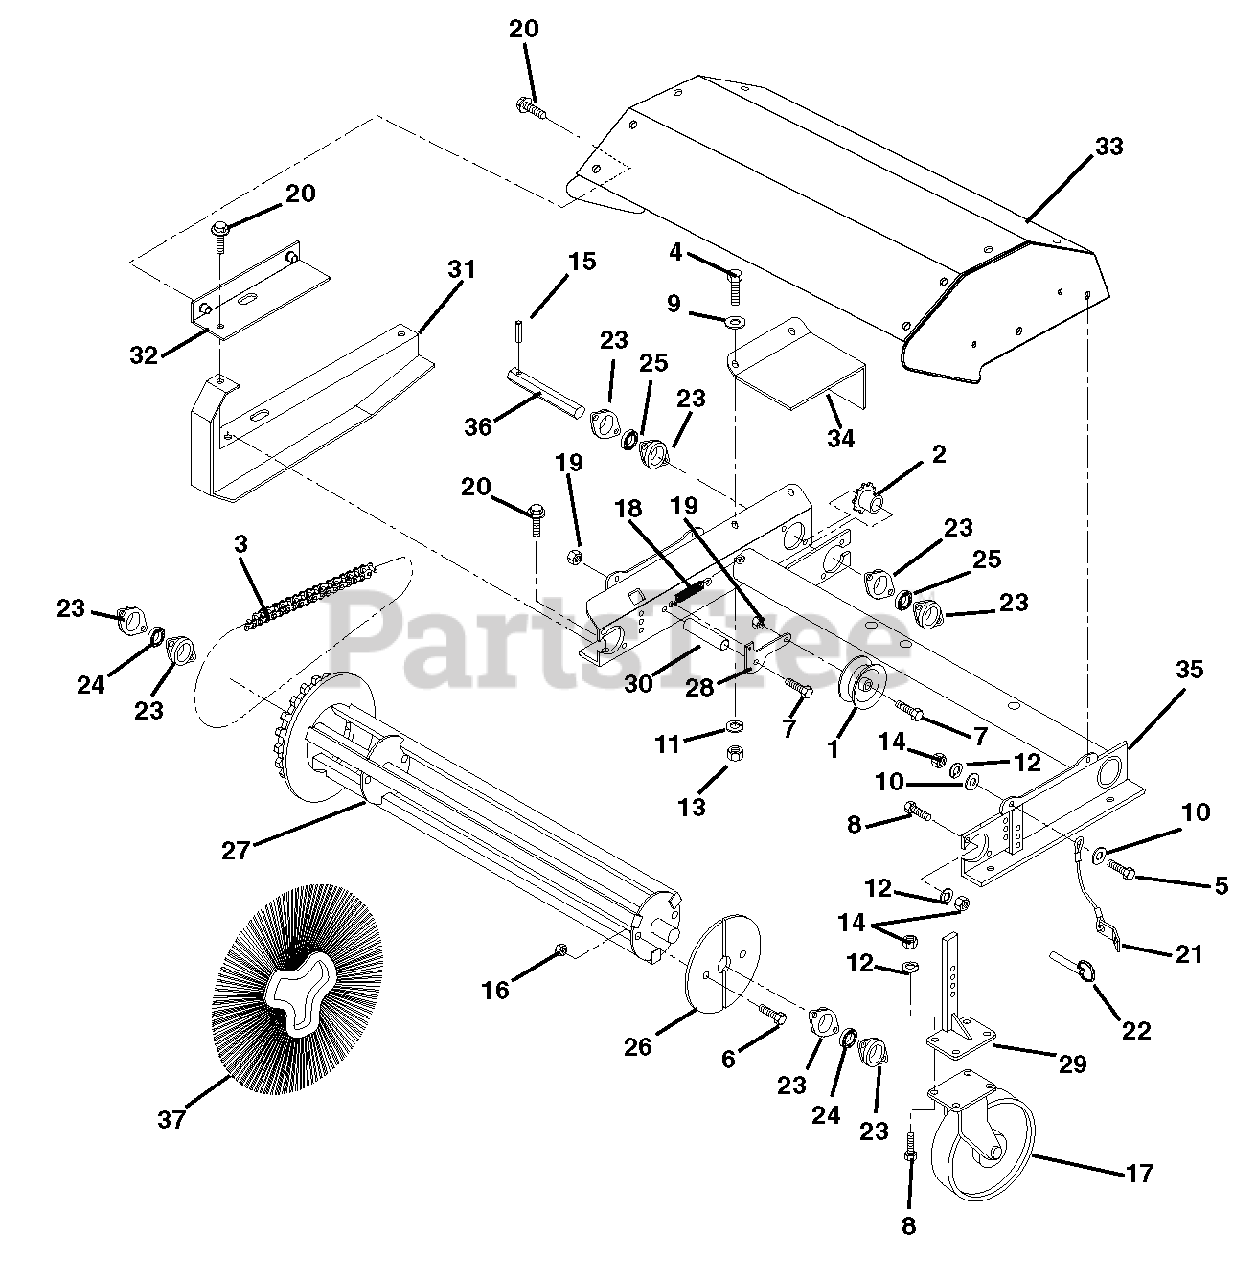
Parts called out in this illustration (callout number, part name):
1	Chain Tightener
2	Sprocket
3	Chain, Assembly #40 x 106
4	Bolt, Hex .25-20 x .75 Grade 5
5	Bolt, Hex .31-18 x 1.00 Grade 5
6	Bolt, Hex .31-18 x 2.25 Grade 5
7	Bolt, Hex .38-16 x 1.50 Grade 5
8	Bolt, Hex .31-18 x .75 Grade 5
9	Washer, Flat Steel .28 x .62 x .065
10	Washer, Flat Steel .31 x .73 x .065
11	Washer, Lock .25 x .062 Regular
12	Washer, Lock .31 x .078 Regular
13	Nut, Hex .25-20
14	Nut, Hex .31-18
15	Pin, Spring Lok .19 x 1.25
16	Nut, Lok Stamped .31-18
17	Wheel, 5 inch Diameter
18	Spring, Tension
19	Nut, Locking Center .38-16
20	Screw, Gear 10.9 M6 x 1-20
21	Lanyard Cable
22	Pin, Spring Ball .375 x 1.00
23	Flange, Spherical
24	Bearing, Spherical
25	Bearing, Ball
26	Retainer Plate
27	Weldment, Core
28	Arm, Idler
29	Weldment, Caster Leg
31	Shield, Chain
32	Shield Chain Top
33	Weldment, Faceted Hood
34	Shield, Input
35	Weldment, Broom Frame
36	Shaft, Hex 20.1" with Hole
37	Set, 24 Section
